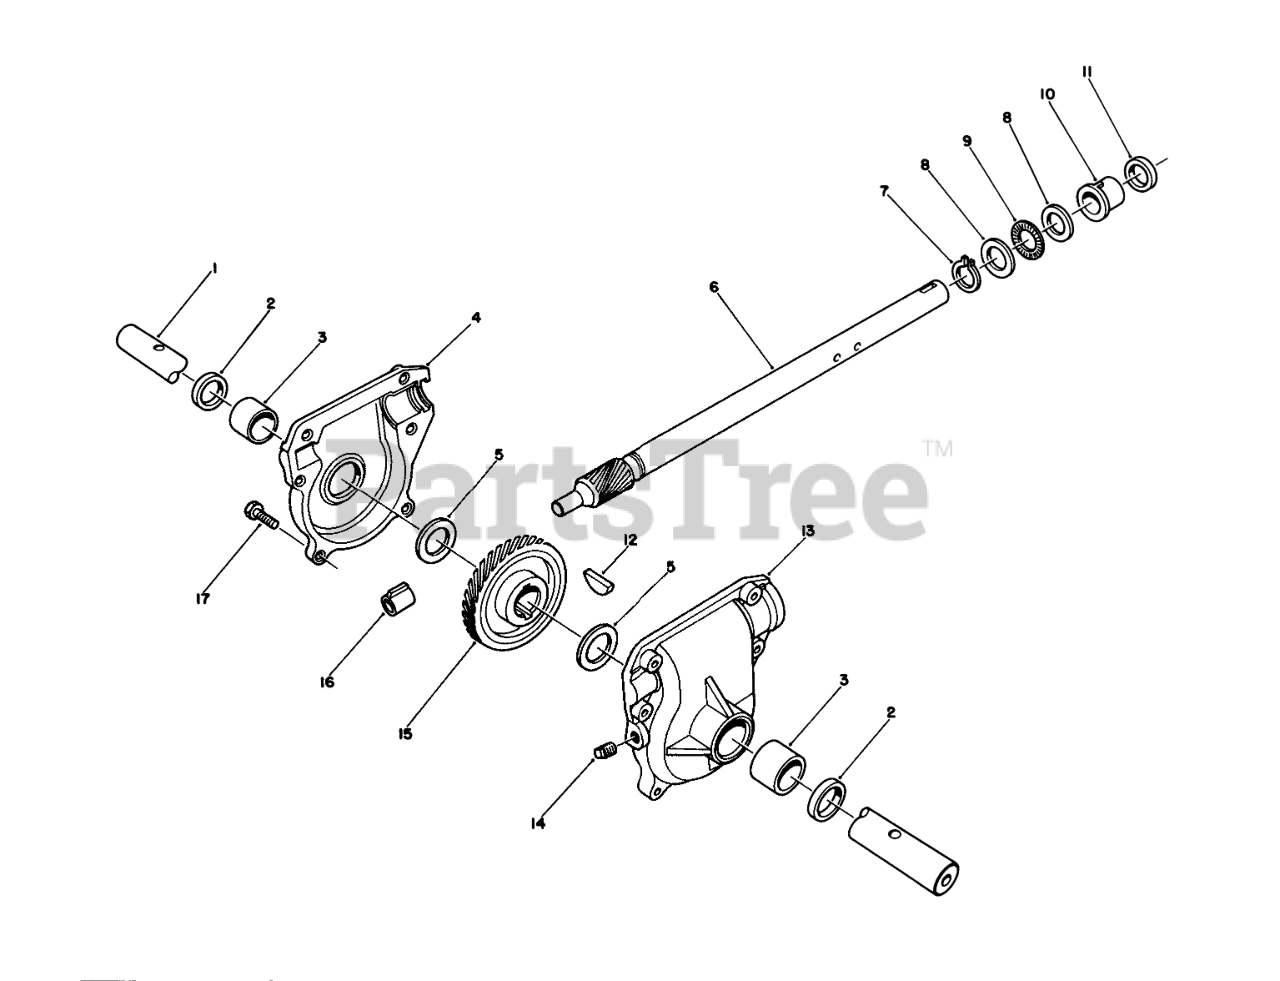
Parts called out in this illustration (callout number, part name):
1	SHAFT-AUGER
2	SEAL-OIL
3	BUSHING
4	Gearcase Assembly-R.H. (Incl. Ref. #2-3)
5	WASHER-THRUST
6	Shaft-Impeller
7	RING-RETAINING, Ext
8	WASHER-THRUST
9	BEARING-THRUST
10	BUSHING-INPUT
11	SEAL-OIL
12	KEY-WOODRUFF
13	Gearcase Assembly-L.H. (Incl. Ref. #2-3)
14	PLUG-PIPE, SQH
15	GEAR-HELICAL
16	BUSHING-WORM
17	SCREW-PPHTF
